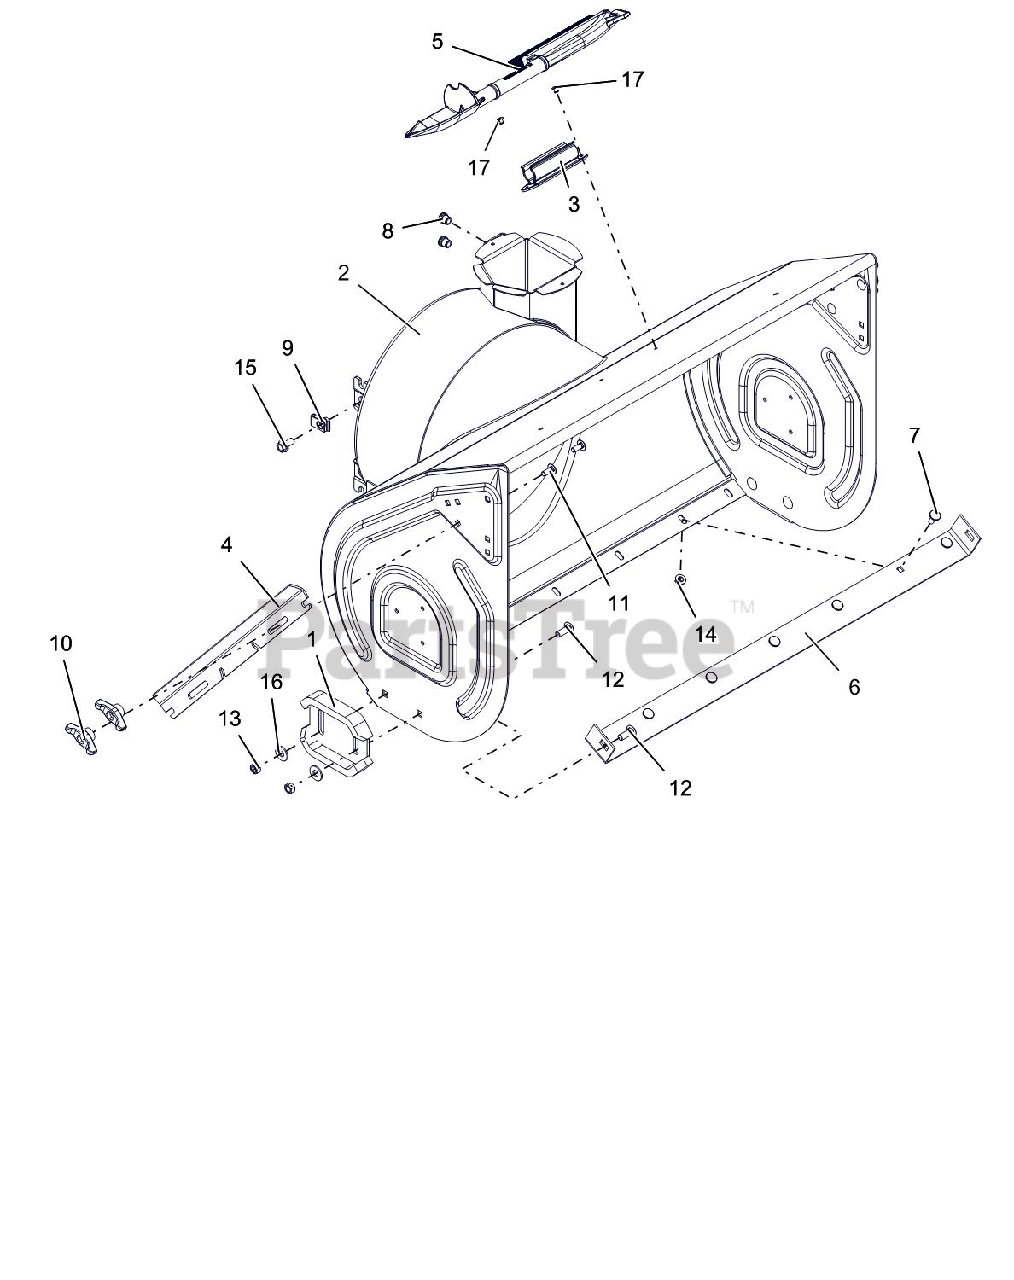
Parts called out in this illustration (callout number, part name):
1	RUNNER, SKID SHOE
2	BLOWER HOUSING W/DECAL 32"
3	MOUNT, SNOW CLEAN OUT
4	CUTTER, DRIFT
5	DEVICE, SNOW CLEAN OUT W/BRUSH
6	BLADE, SCRAPER-32"
7	BOLT, MODIFIED HEAD CARRIAGE
8	NUT, THREADED INSERT .38-16
9	NUT-RTNR .375-16X.37
10	KNOB,WING .31-18 UNC NYL/TALC
11	@BLT-RHDSSQNK .31-18X.75 G5YZ
12	@BLT-RDHDSHSQNK.38-16X1.0 G5YZ
13	@NUT-LK-CTR .38-16 YWZC
14	@NUT-LK-TOP-FLG .31-18 YWZC
15	BLT-SERHFWH .38-16X.75 YWZC
16	@WSHR-FL-STL.438X1.00X.083 YWZ
17	RVT-POP .187 YZ
